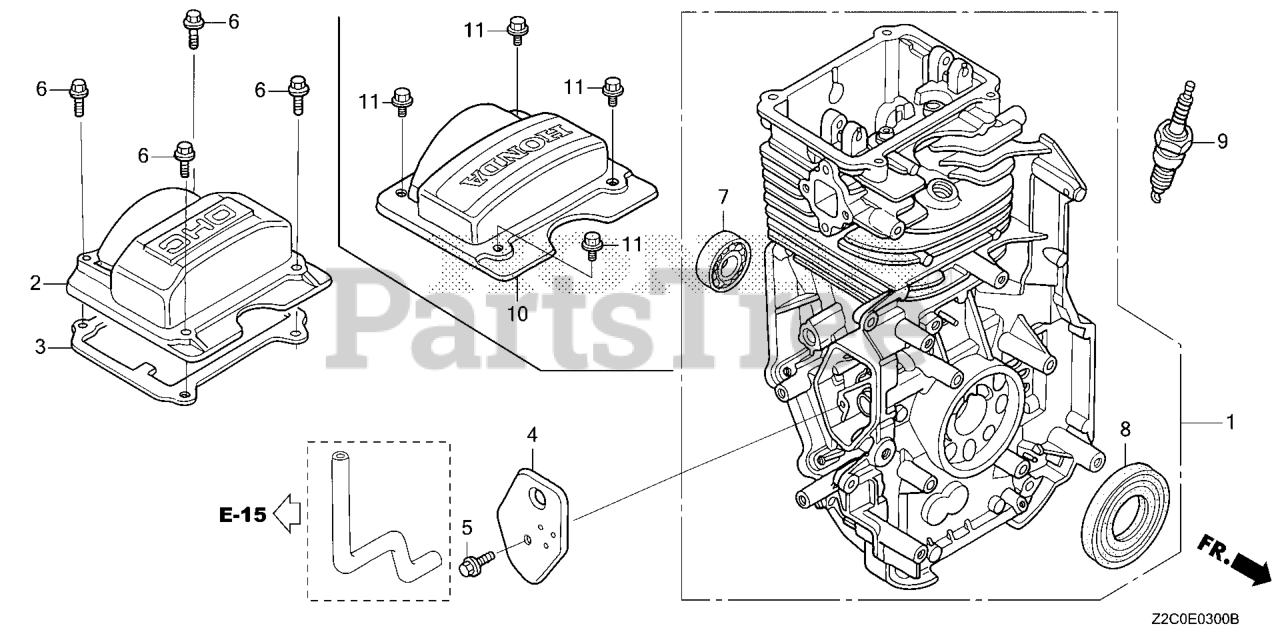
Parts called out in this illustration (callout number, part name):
1	CYLINDER ASSY.
2	COVER, CYLINDER HEAD
4	COVER, BREATHER (Honda Code 5580006). (BREATHER VALVE ASSY.)
5	BOLT, FLANGE (6X14)
6	BOLT, FLANGE (6X12) (CT200)
7	BEARING, RADIAL BALL
8	OIL SEAL (25.4X74X6)
9	SPARK PLUG (BPR6ES) (NGK)
10	COVER, CYLINDER HEAD
11	BOLT, FLANGE (6X12) (CT200)
